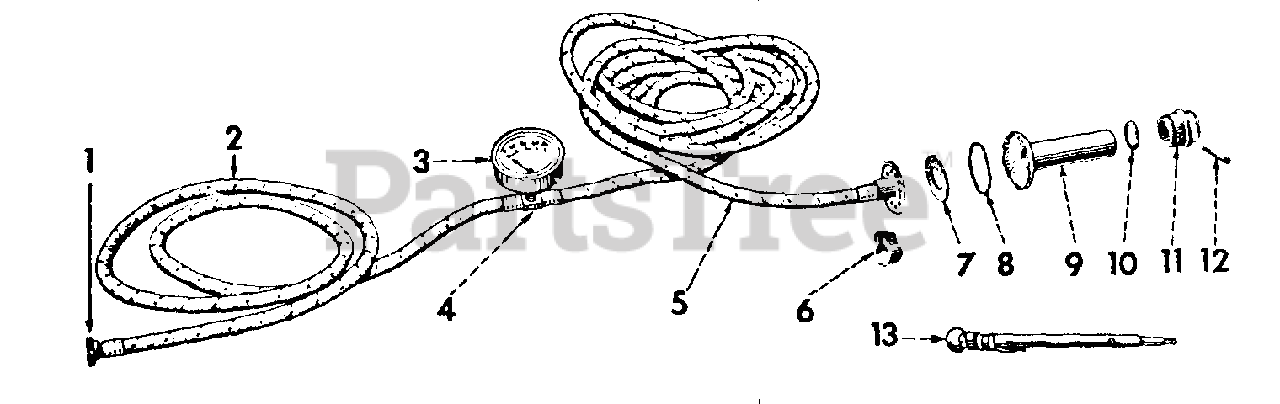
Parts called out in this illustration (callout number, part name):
1	CONNECTOR, PUMP
2	HOSE, 4 FT. TIRE PUMP
3	GAGE, AIR PRESSURE
4	CONNECTOR AIR PRESSURE GAGE
5	HOSE 12 FOOT TIRE PUMP
6	CLAMP, HOSE
7	DISC, RUBBER
8	WASHER, FIBER
9	SHELL, LONG
10	WASHER, INSIDE ADAPTER RUBBER
11	ADAPTER
12	SCREW, ATTACHING
13	GAGE TIRE PRESSURE
